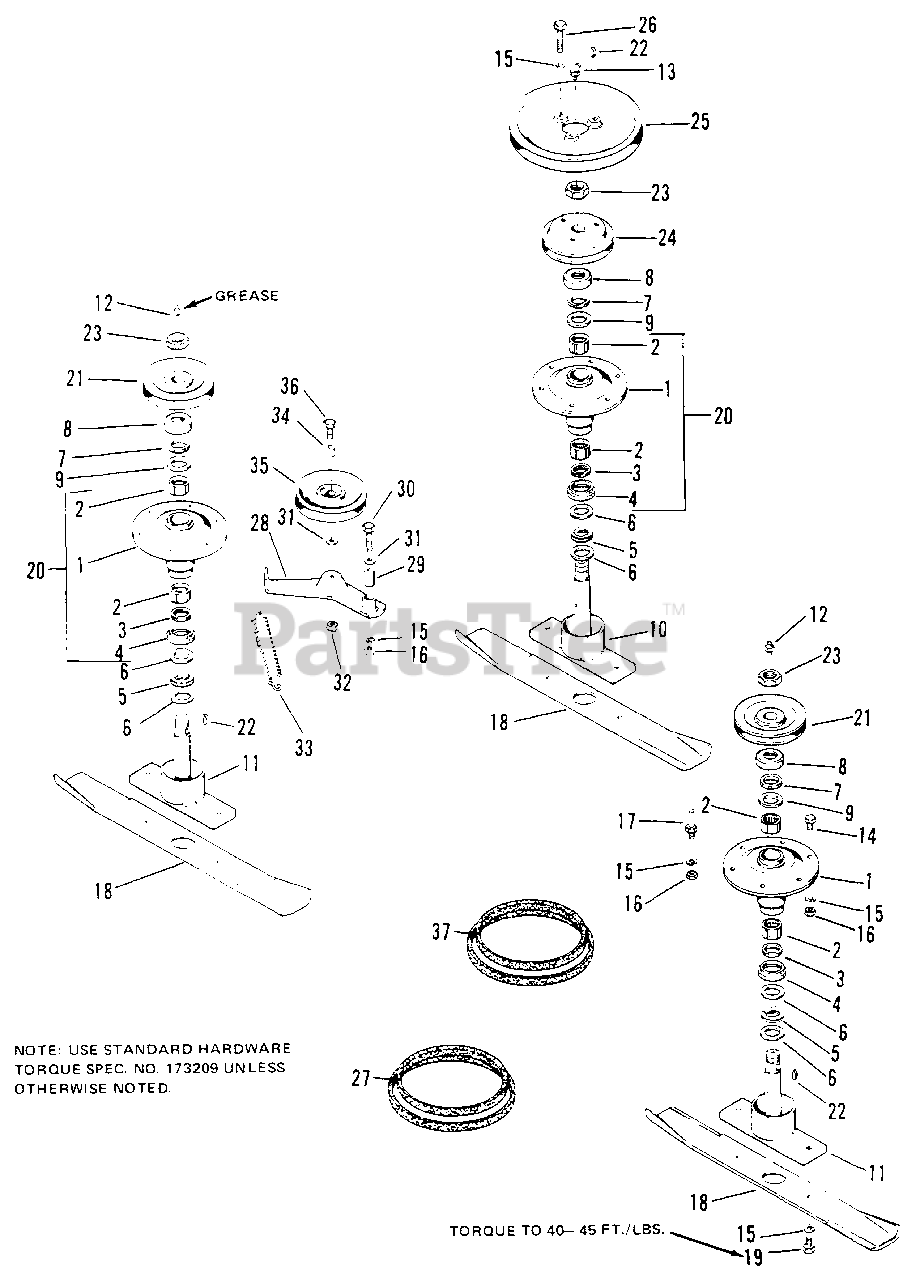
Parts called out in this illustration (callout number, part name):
1	TUBE SUB ASSY, Arbor
2	BEARING, Roller
7	BEARING, Thrust
9	WASHER, Thrust
10	ARBOR ASSY, Drive Center
11	ARBOR ASSY, Side
12	FITTING, Lube, 1/4-28
13	FITTING, Lube, 1/4-28
14	CAPSCREW, Hex Hd., 3/8-16 x 1
15	LOCKWASHER, Spring, 3/8
16	NUT, Hex, 3/8-16
19	CAPSCREW, Hex Hd, 3/8-16 x 1, Gr. 8
20	TUBE ASSY, Arbor Drive
22	KEY, Hi Pro, 3/16 x 5/8
23	NUT, Hex, Full Lock, Jam, 7/8-14
26	CAPSCREW, Hex Hd., 3/8-16 x 2
27	V-BELT, 116.1"
28	LEVER ASSY, Idler
29	RACE, Inner
30	CAPSCREW, Hex Hd., 3/8-16 x 1-3/4
31	WASHER, Plain, 5/16
32	NUT, Hex Lock, Jam, 3/8-16
33	SPRING, Tension
35	PULLEY, Idler
36	SCREW, Special
37	BELT, "V", PTO
